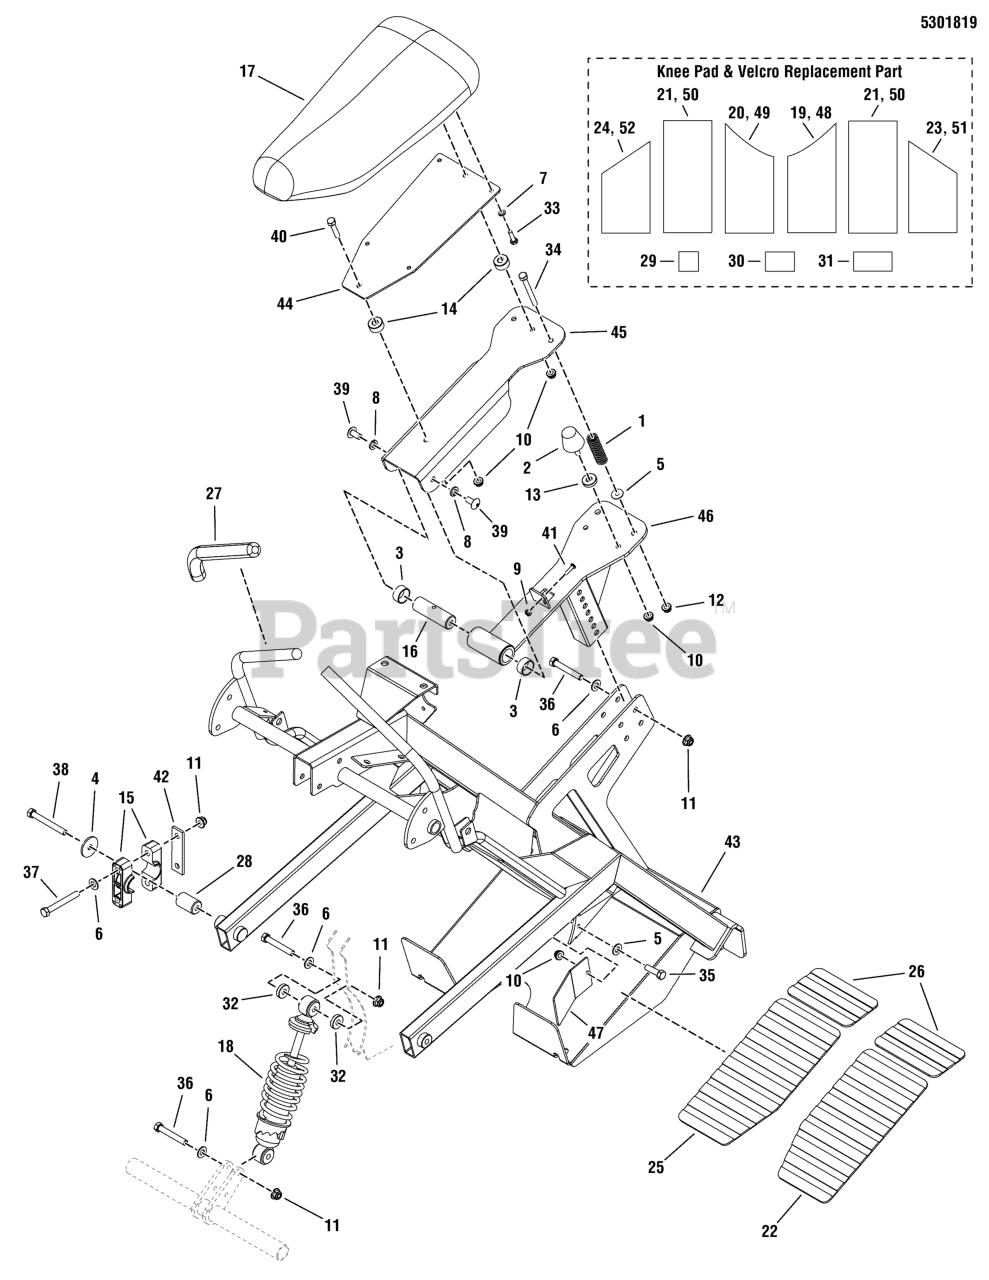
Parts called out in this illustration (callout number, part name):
1	STAINLESS STEEL COMP. SPRING
2	BUMPER, RUBBER 5/16-18
3	BUSHING, 1.00 X 1.13 X 1.38, PLASTIC
4	WASHER, 1/2 USS
5	WASHER, 5/16" SAE
6	WASHER, 3/8 SAE
7	WASHER, 1/4 LOCK
8	WASHER, 3/8 SPLIT LOCK
9	NUT, #10-24 HEX NYLON LOCK
10	NUT, 5/16-18 HEX NYLOCK FLANGE
11	NUT, 3/8-16 HEX NYLOCK FLANGE
12	ACORN NUT, 5/16-18 S/S
13	SPACER, .39 X 1.00 X .25
14	SPACER, .39 X 1.00 X .50
15	PIVOT BLOCK, PLASTIC
16	SPACER, 1.00 X 3.25 THRD BOTH ENDS
17	SEAT, EVOLUTION
18	SHOCK ABSORBER
19	KNEE PAD, INNER RH, EVOLUTION 36"/48"
20	KNEE PAD, INNER LH, EVOLUTION 36"/48"
21	KNEE PAD, CENTER, EVOLUTION 36"/48"
22	SAFETY WALK, EVOLUTION 36"
23	KNEE PAD, OUTER RH, EVOLUTION 48/52
24	KNEE PAD, OUTER LH, EVOLUTION 48/52
25	SAFETY WALK, 6.00 X 11.25
26	SAFETY WALK, 3.5 X 6.00
27	FOAM, GRIP, 3/4" ID X 12" LG X .187 BLK
28	SPACER, .515 X 1.00 X 1.22, YZ
29	VELCRO, 2" X 2", HOOK MATERIAL
30	VELCRO, 2" X 3", HOOK MATERIAL
31	VELCRO, 2" X 4", HOOK MATERIAL
32	SPACER, .390 X 1.00 X .188, YZ
33	BOLT, 1/4-20 X 1" GD5 CZ
34	BOLT, 5/16-18 X 3-1/4 GD5
35	BOLT, 5/16-18 X 1 GD5 YZ
36	BOLT, 3/8-16 X 2-1/2" GD5 CZ
37	BOLT, 3/8-16 X 2-3/4" GD5 CZ
38	BOLT, 1/2-20 X 2-1/4 GD5 CZ
39	BOLT, 3/8-16 X 3/4,ALLEN BUTTON
40	BOLT, 5/16-18 X 1-3/4, CARRIAGE
41	SCREW, #10-24 X 3/4 ROUND PHILLIPS
42	PLATE, PIVOT BLOCK SUPPORT - BLK
43	WELD, OPERATOR COMPARTMENT, 48 - RED
44	PLATE, SEAT RAIL ADAPTER - RED
45	PLATE, SEAT MOUNT, TOP - RED
46	WELD, SEAT MOUNT - RED
47	GUARD, FOOT, EVO 36-48 - RED
48	KNEE PAD, INNER RH, EVOLUTION 36/48
49	KNEE PAD, INNER LH, EVOLUTION 36/48
50	KNEE PAD, CENTER, EVOLUTION 36/48
51	KNEE PAD, OUTER RH, EVOLUTION 36/48
52	KNEE PAD, OUTER LH, EVOLUTION 36/48
53	NUT, 1/2-20 HEX NYLOCK FLANGE
